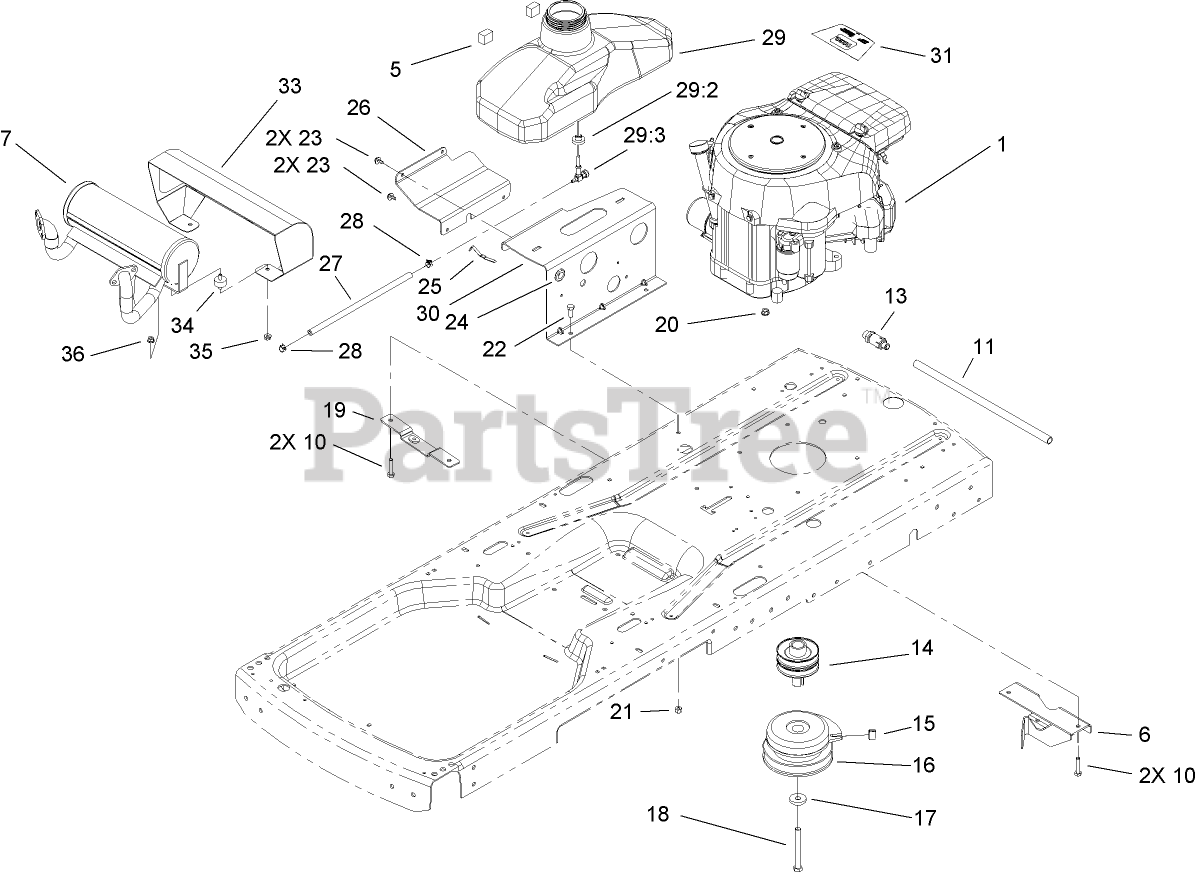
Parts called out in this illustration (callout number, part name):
1	Loose Parts Package
5	FOAM-SWITCH, SEAT
6	BRACKET-PIVOT
7	MUFFLER
10	SCREW-HH
11	TUBE-DRAIN, OIL
13	VALVE-DRAIN, OIL
14	PULLEY-ENGINE
15	BUMPER
16	CLUTCH-ELECTRIC
17	WASHER
18	SCREW-HH
19	PLATE-MOUNT, IDLER
20	NUT-HF
21	NUT-LOCK, NI
22	SCREW-HH
23	SCREW-HHFTF
24	GROMMET
25	SPRING
26	PLATE-SUPPORT
27	HOSE-FUEL
28	CLAMP-HOSE
29	GAS TANK ASM
29:2	BUSHING
29:3	VALVE-FUEL
30	PLATE-TANK
34	ISOLATOR-RUBBER
35	NUT-HHF
36	NUT-HF
